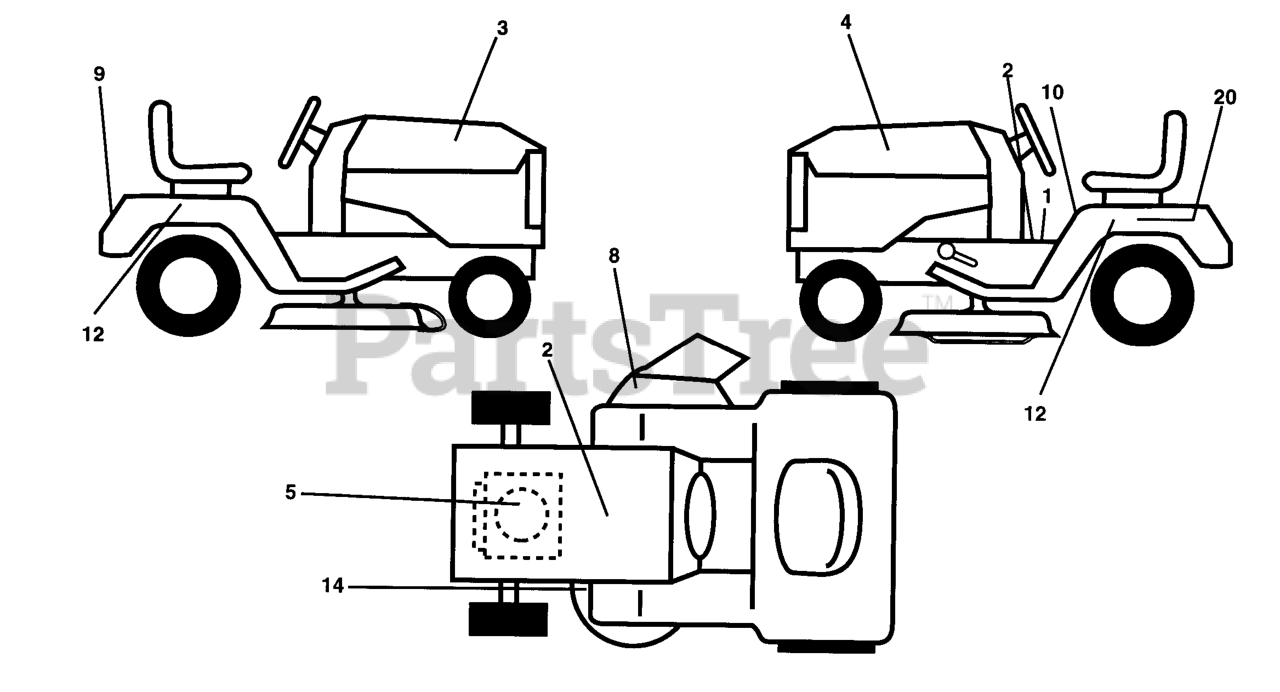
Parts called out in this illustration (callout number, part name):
2	DECAL, BATTERY DANGER
3	DECAL, HOOD LH YTH150
4	DECAL, HOOD RH YTH150
5	DECAL ENGINE KOHLER 15HP
8	DECAL WARNING (ENGLISH/FRENCH)
9	DECAL FENDER HUSQ
10	DECAL FENDER DANGER
14	DECAL V-BELT SCHEMATIC
